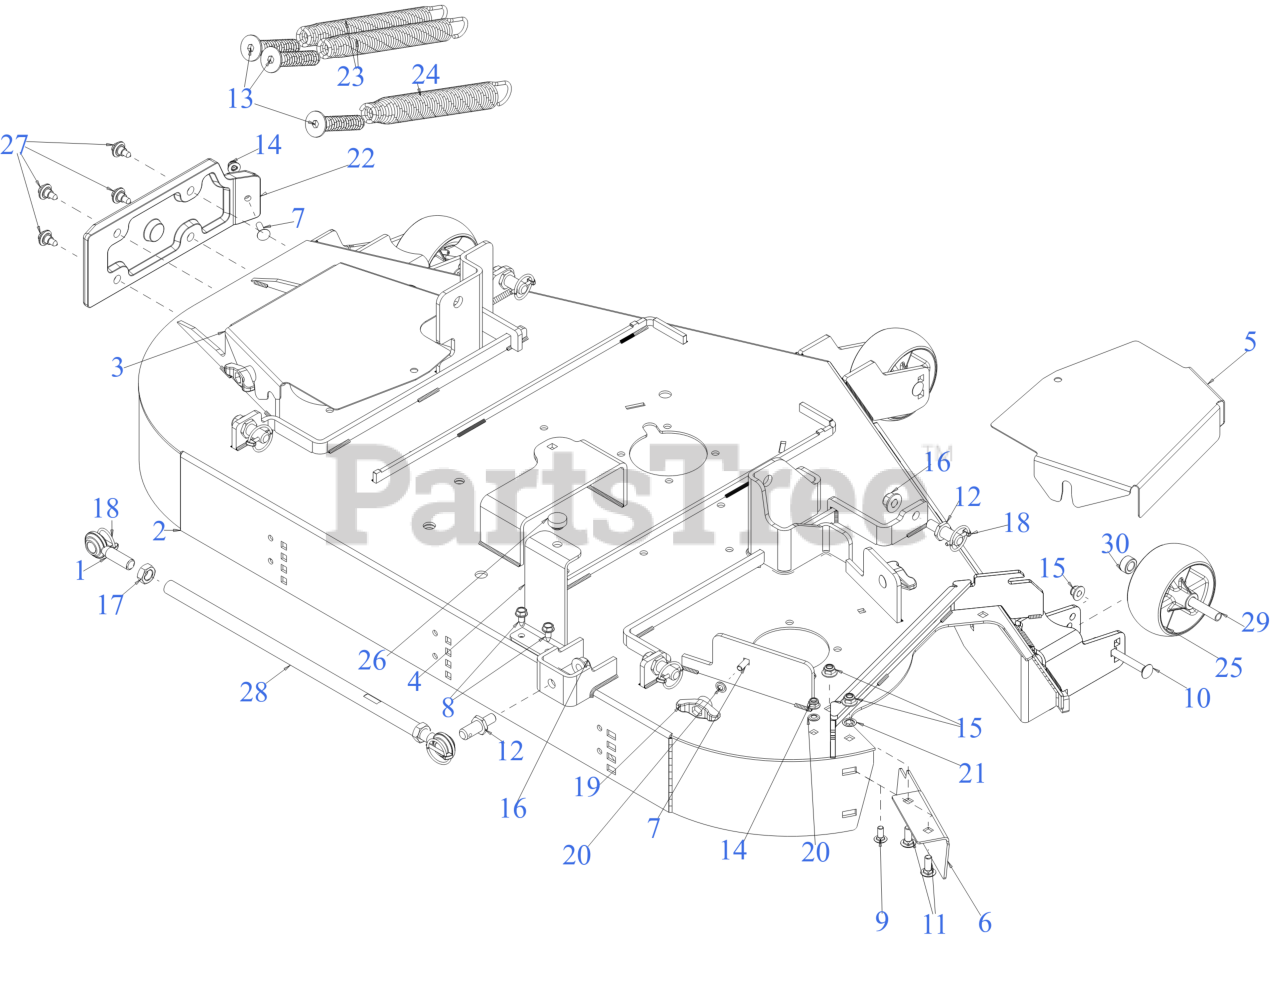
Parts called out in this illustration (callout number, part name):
1	MALE ROD END
2	54" FAB DECK
3	BELT COVER (LH)
4	DECK STOP BRACKET
5	BELT COVER (RH)
6	BAFFLE
7	CARRIAGE BOLT 5/16-18 x 1.00
8	SCREW 5/16-18 x .750
9	CARRIAGE BOLT 5/16-18 x .75
10	CARRIAGE BOLT 3/8-16 x 4.00 GR5
11	CARRIAGE BOLT 3/8-16 x 1.00 GR5
13	SPRING INSERT SCREW
14	FLANGE LOCK NUT 5/16-18
17	HEX JAM NUT 5/8-18
18	LYNCH PIN .1875
19	WING KNOB 5/16-18
20	PUSH NUT
21	PUSH NUT
22	DECK SKID PLATE (LH)
23	EXTENTION SPRING 1.20 x 11.35
24	EXTENSION SPRING 1.44 OD x 11.36
25	DECK WHEEL
26	RUBBER BUMPER 1.000 x .313
27	SHOULDER SCREW .43X.29X5/16-18 TT
28	TUBE .565 X .750 X 18.75"LG
29	SPACER .38X.49X3.05LG
30	SPACER-.505 1D
